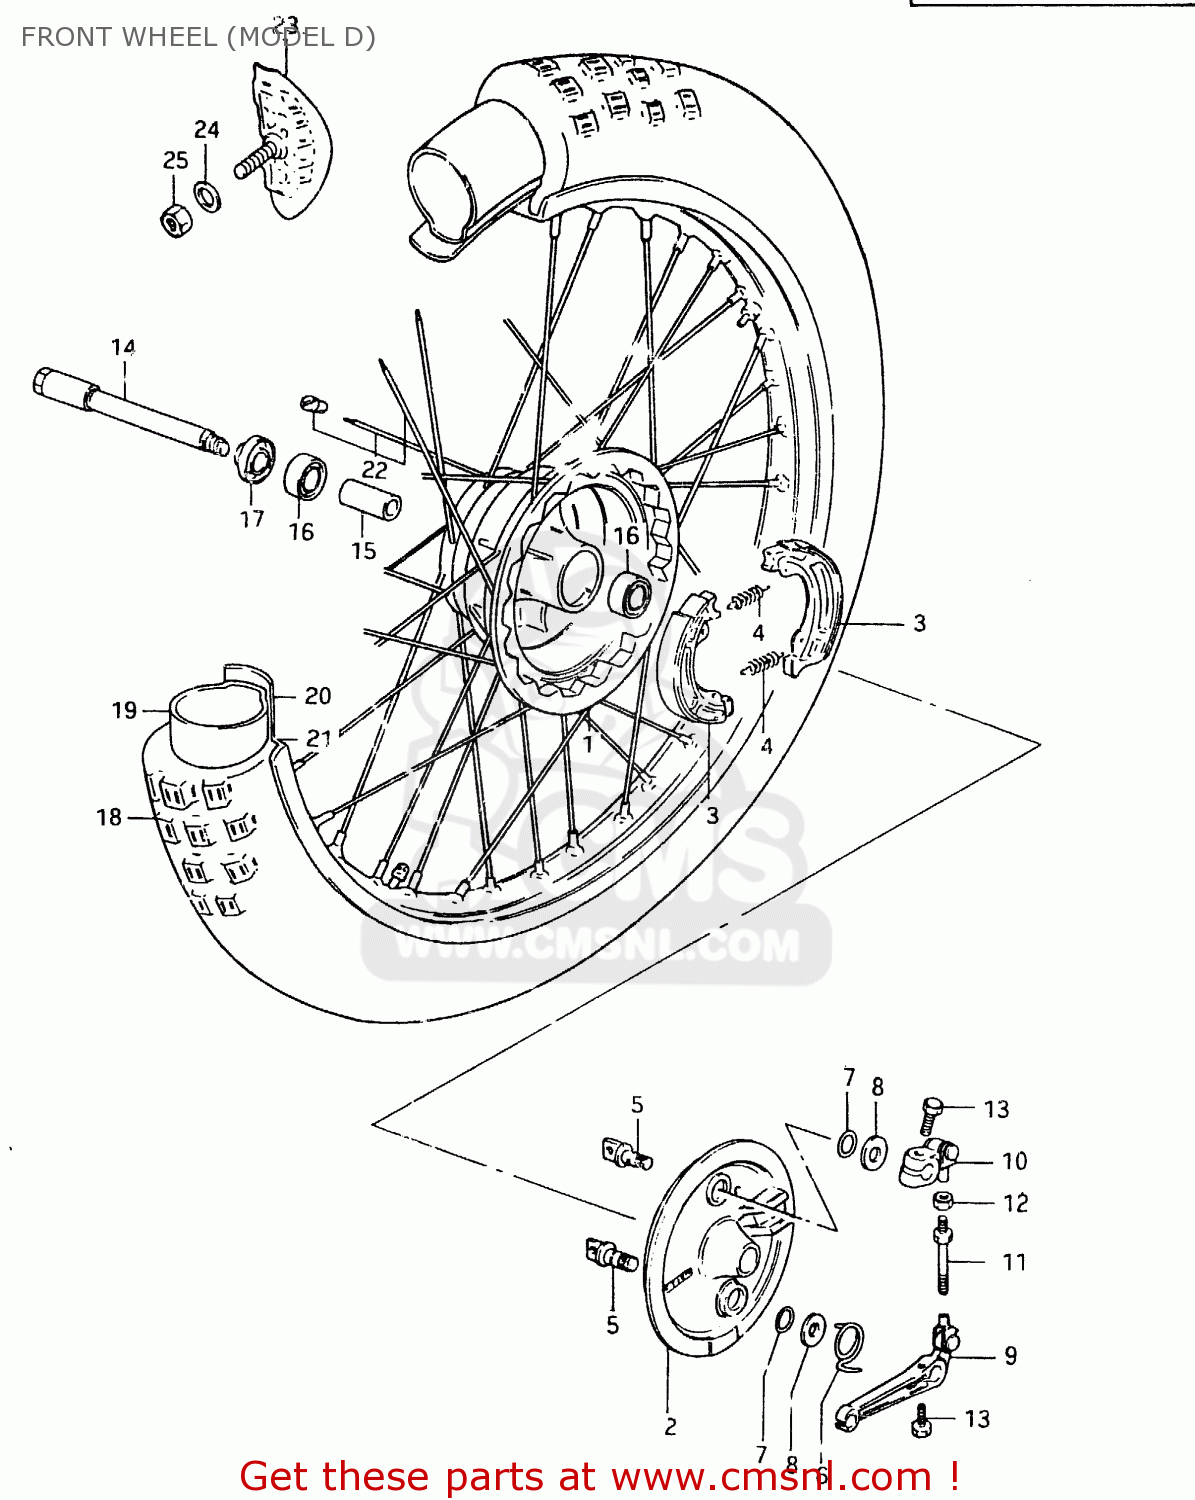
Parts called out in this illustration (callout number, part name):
1	HUB,FRONT
2	PANEL,FRONT HUB
3	SHOE,BRAKE (MCA)
4	SPRING
5	CAM,FRONT BRAKE
6	SPRING
7	O-RING (D:2 ID13.8)
8	WASHER (14.2X22X1)
9	LEVER, BRAKE CAM
10	LEVER ASSY, BRAKE CAM, NO.2
11	ROD,BRAKE CAM LEVER CONNECTION
12	NUT 6MM
13	BOLT
14	AXLE,FRONT
15	SPACER,FRONT HUB BEARING
16	BALL BEARING 15X35X11
17	SPACER,FRONT AXLE,RIGHT
18	TIRE,FRONT
19	TUBE,INNER
20	PROTECTOR,WHEEL,INNER
21	RIM,FRONT WHEEL
22	SPOKE SET,FRONT
23	STOPPER,BEAD
24	WASHER
25	NUT 8MM
